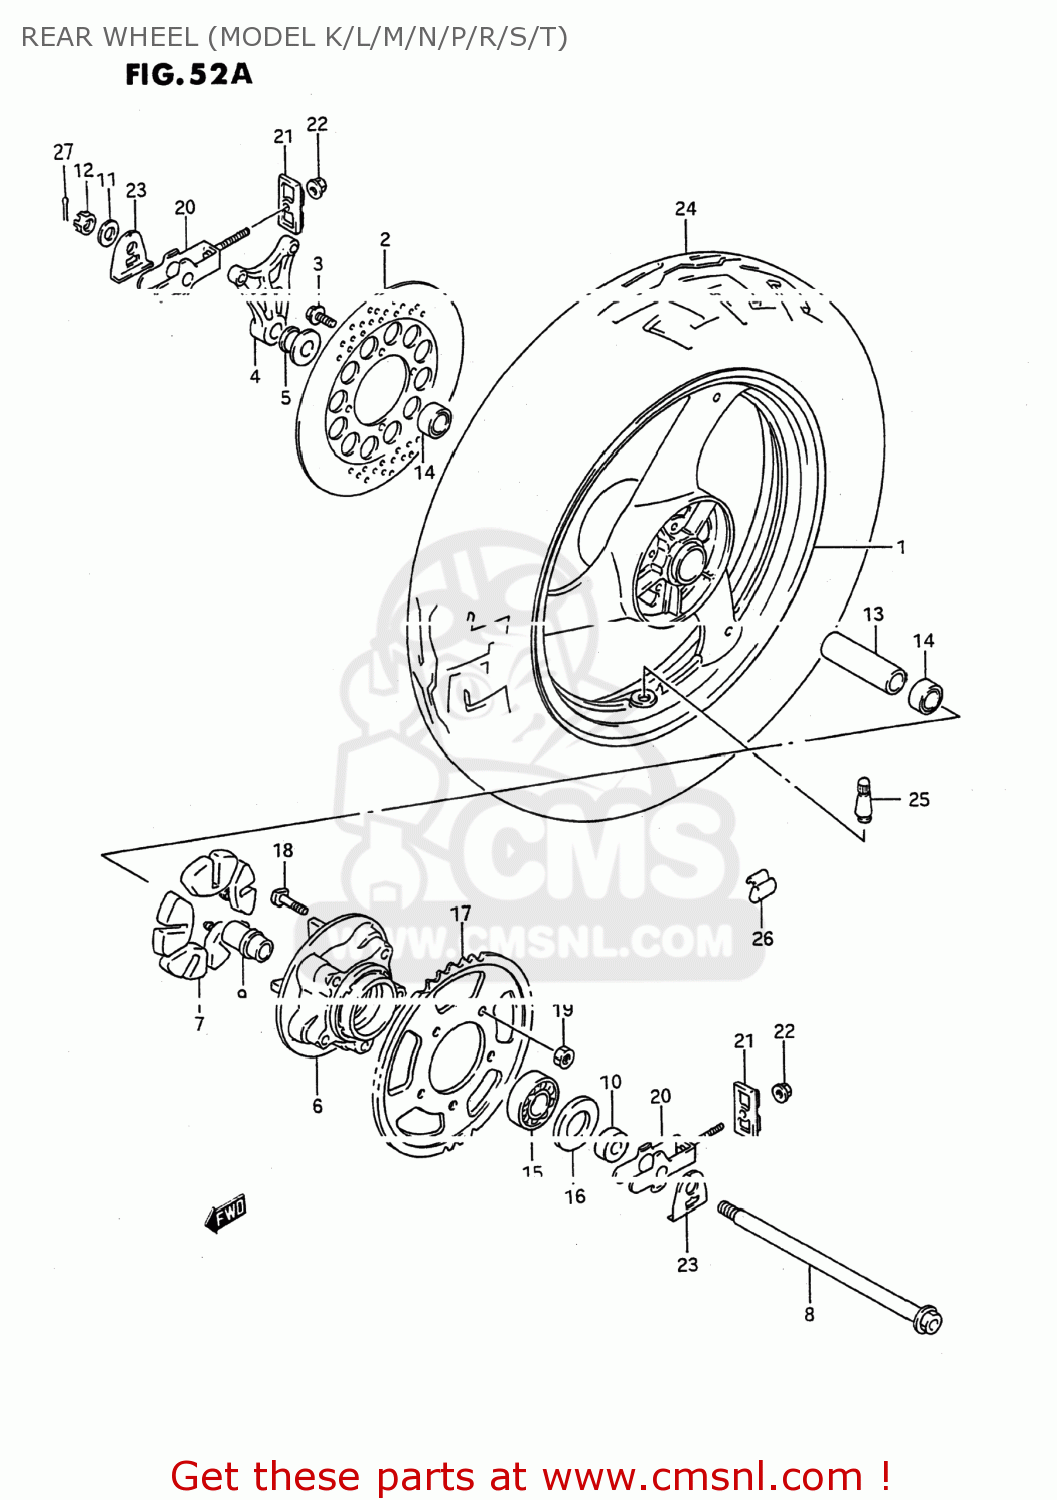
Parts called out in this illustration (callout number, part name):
1	WHEEL,REAR (MT3.50X17)
2	DISC,RR BRAKE
3	BOLT
4	BRACKET,RR,CALIPER
5	SPACER,RR AXLE,R
6	DRUM,RR SPROCKET MOUNTING
7	ABSORBER,RR HUB SHOCK
8	AXLE,REAR
9	RETAINER,RR SPROCKET DRUM
10	SPACER,RR AXLE,L
11	WASHER (17X30X3.2)
12	NUT
13	SPACER(17.5X25X88)
14	BEARING
15	BEARING(25X62X17)
16	SEAL,OIL(35X62X8)
17	SPROCKET,RR(NT:46-530)
18	BOLT
19	NUT
20	ADJUSTER,CHAIN
21	PLATE,CHAIN ADJUSTER GUIDE
22	NUT
23	WASHER,CHAIN ADJUSTER
24	TIRE 140/80 VB17 V270
25	VALVE,TIRE
26	BALANCER,WHEEL
27	PIN,COTTER
